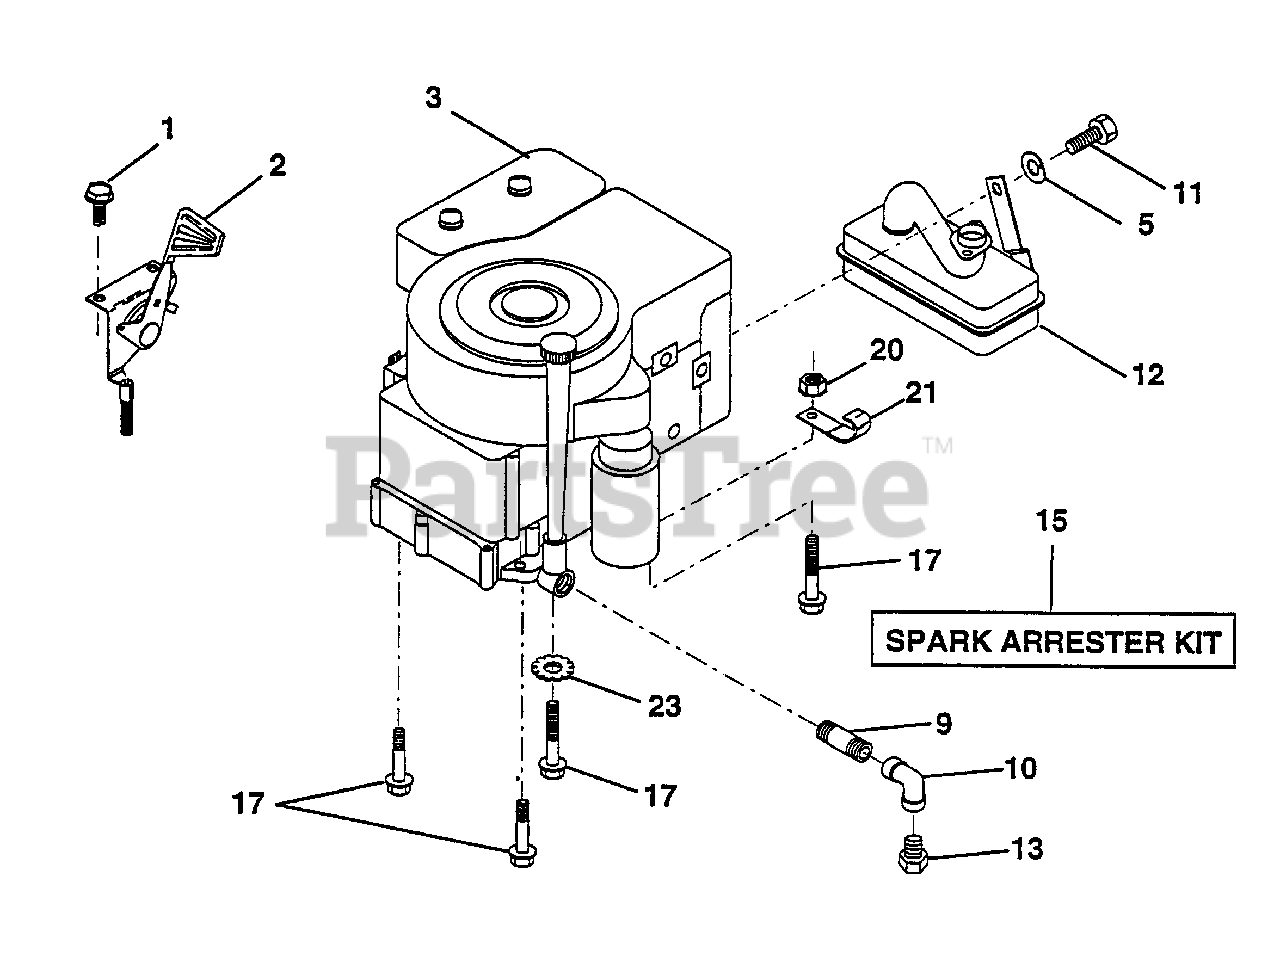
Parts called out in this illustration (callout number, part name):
1	Screw, Hex Head, Thread Cutting 1/4-20 x 1/2
2	Control, Throttle
3	Engine, Kohler, 12.5 HP, Model
5	Washer, Lock, Heavy Helical Spring 5/16
9	Nipple Pipe
10	Elbow
11	Bolt, Hex, Fin. 5/16 -18 x 1/2
13	Oil Drain Plug
15	Arrester, Spark
17	Bolt Hex
20	Nut, Hex, Keps 3/8-16
21	Clip, Fuel Line
23	Washer Lock Ext. Tooth 3/8
